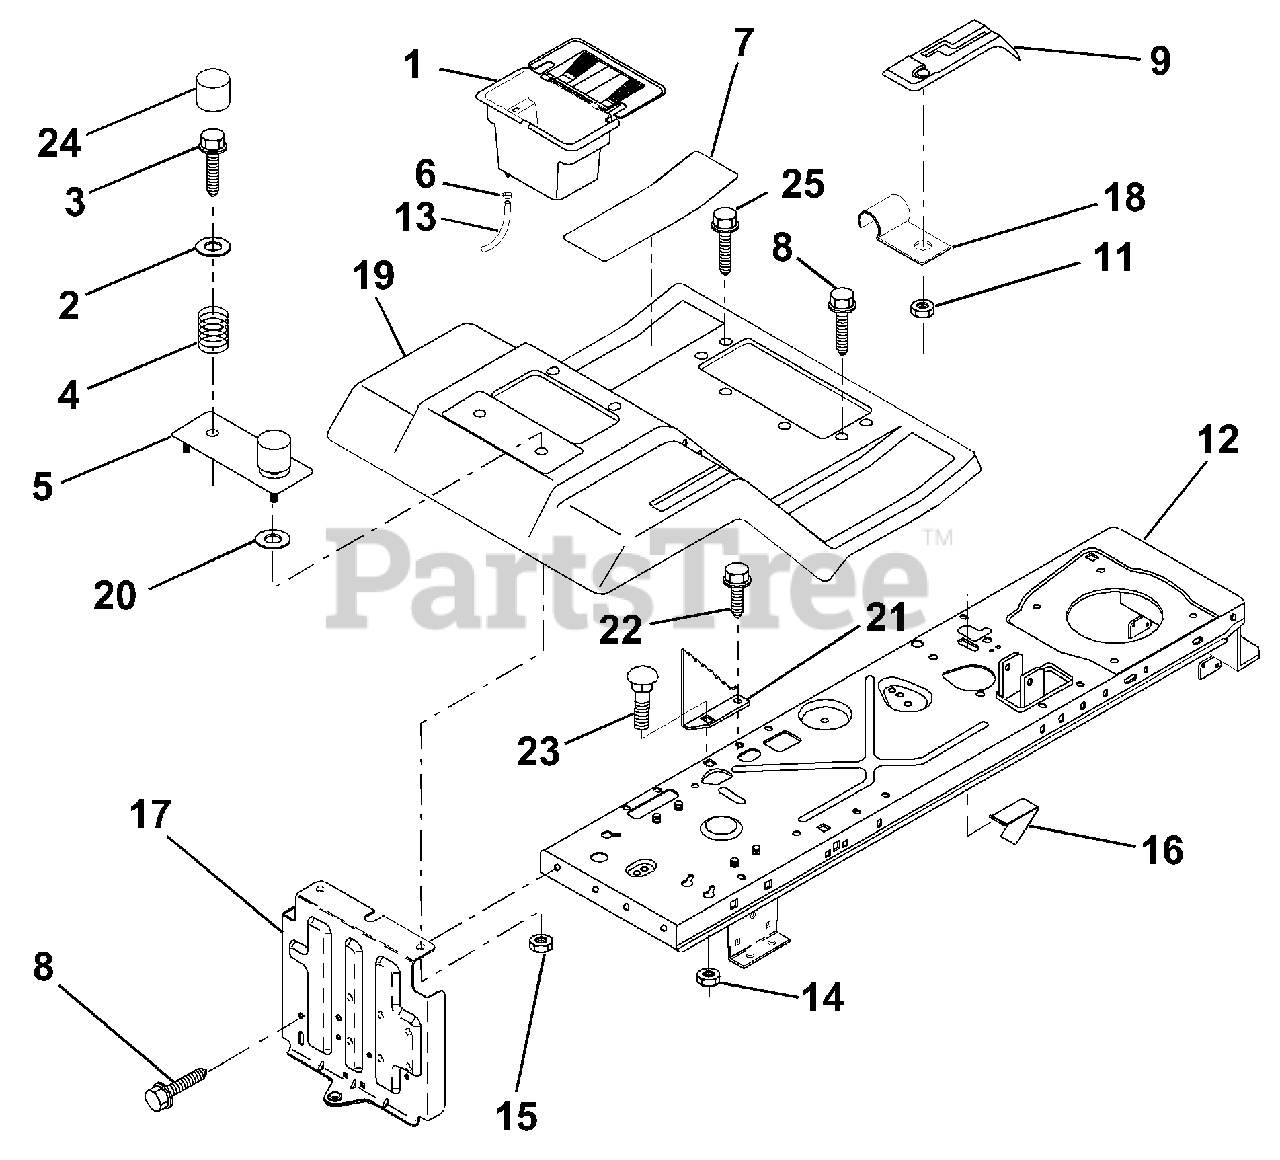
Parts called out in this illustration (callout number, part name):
1	Case Asm. Battery
2	Washer 13/32 x 1-1/4 x 12 Ga.
3	Screw Thdrol. 3/8-16 x 3/4
4	Spring seat
5	Plate Asm. Pnt Battery Fender
6	Clamp Hose Olive
7	Pad Footrest Rubber Deluxe
8	Screw Thdrol. 5/16-18 x 3/4
9	Console Shf. 6sp W/Ign.
11	Nut Self Thd. Wsh-Hd 1/4
12	Chassis Asm. Weldment
13	Tube Plastic
14	Nut Crownlock 5/16-18 UNC
15	Nut Keps Hex 1/4-20
16	Switch Actuator
17	Drawbar Asm.
18	Clip Insulated
19	Fend/Foot Asm. Pnt Shf. Fnd.
20	Washer 9/32 x 7/8 x 13 Ga.
21	Bracket Stop Depth
22	Screw Thdrol 5/16-18 x 1/2
23	Bolt Rdhdsqnk. 5/16-18 x 3/4
24	Cap Spring
25	Scr-Hex Wsh Rol 5/16-18 x 1
